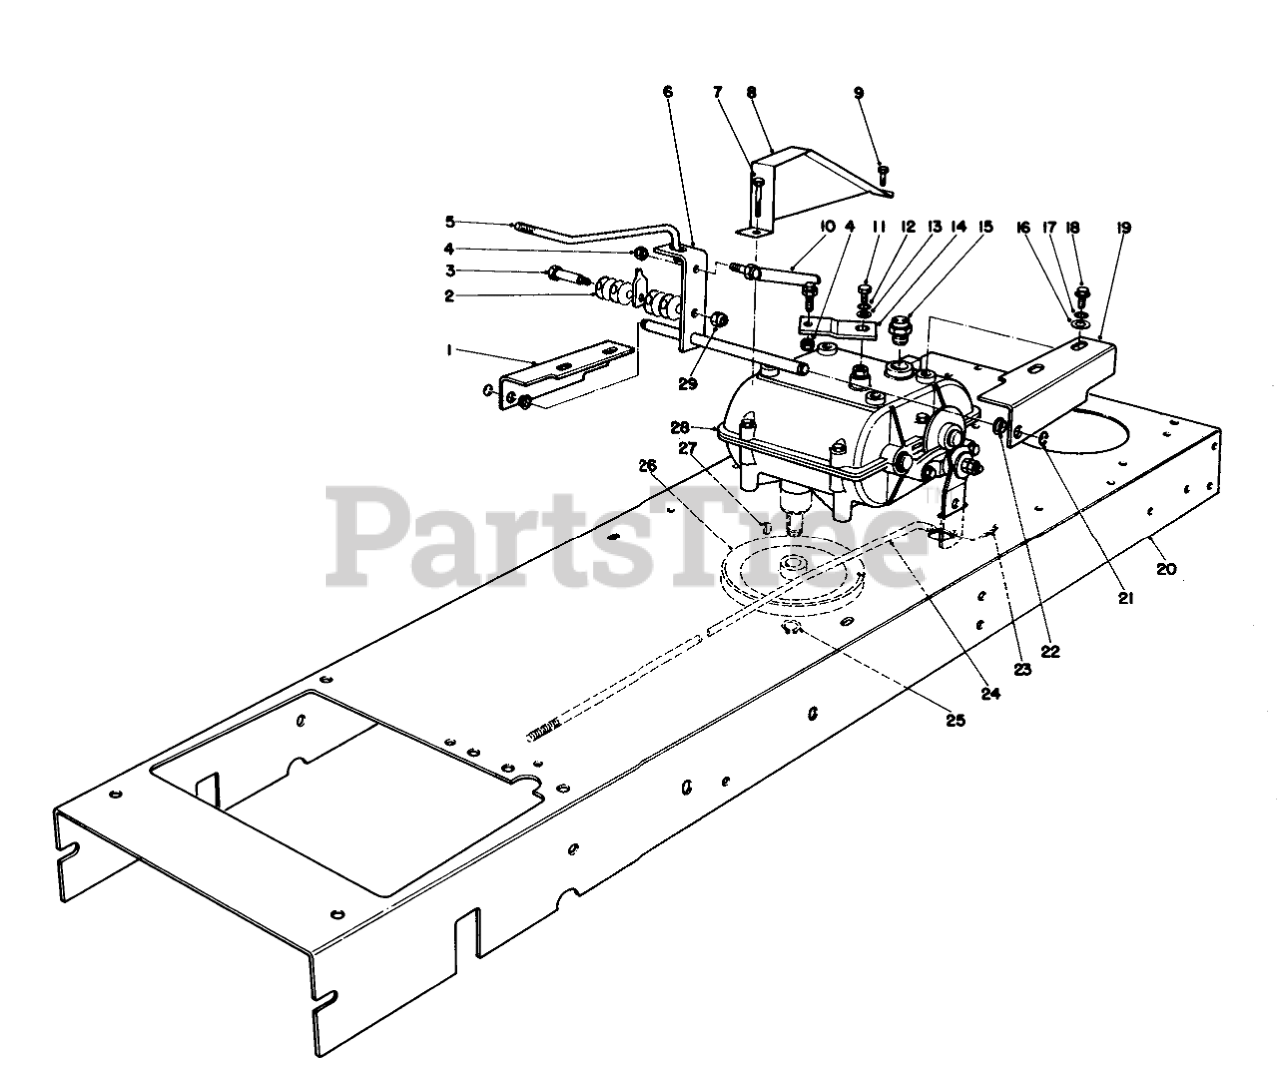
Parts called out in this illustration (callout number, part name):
1	Bracket-Shift R.H.
2	WASHER-BELLEVILLE
3	BOLT-SHOULDER
4	NUT-LOCK, NI
5	Lever-Shift
6	SHIFT LEVER WA B
7	SCREW-HH
8	CHAIN GUARD R
9	SCREW-HH
10	TIE ROD SHIFT
11	SCREW-HH
12	WASHER-LOCK
13	WASHER-FLAT
14	SHIFT LEVER LINK BO
15	NEUTRAL SWITCH
16	WASHER-PLAIN
17	WASHER-LOCK
18	SCREW-HWHTF
19	51-1710T BRKT B
20	Frame-Main
21	E-RING EXTERNAL
22	NYLINER #7L2FF TYPE 7
23	PIN-COTTER
24	Rod-Brake
25	RING-SNAP, EXTERNAL
26	PULLEY
27	KEY-WOODRUFF
28	TRANSMISSION
29	NUT-LOCK, NI
